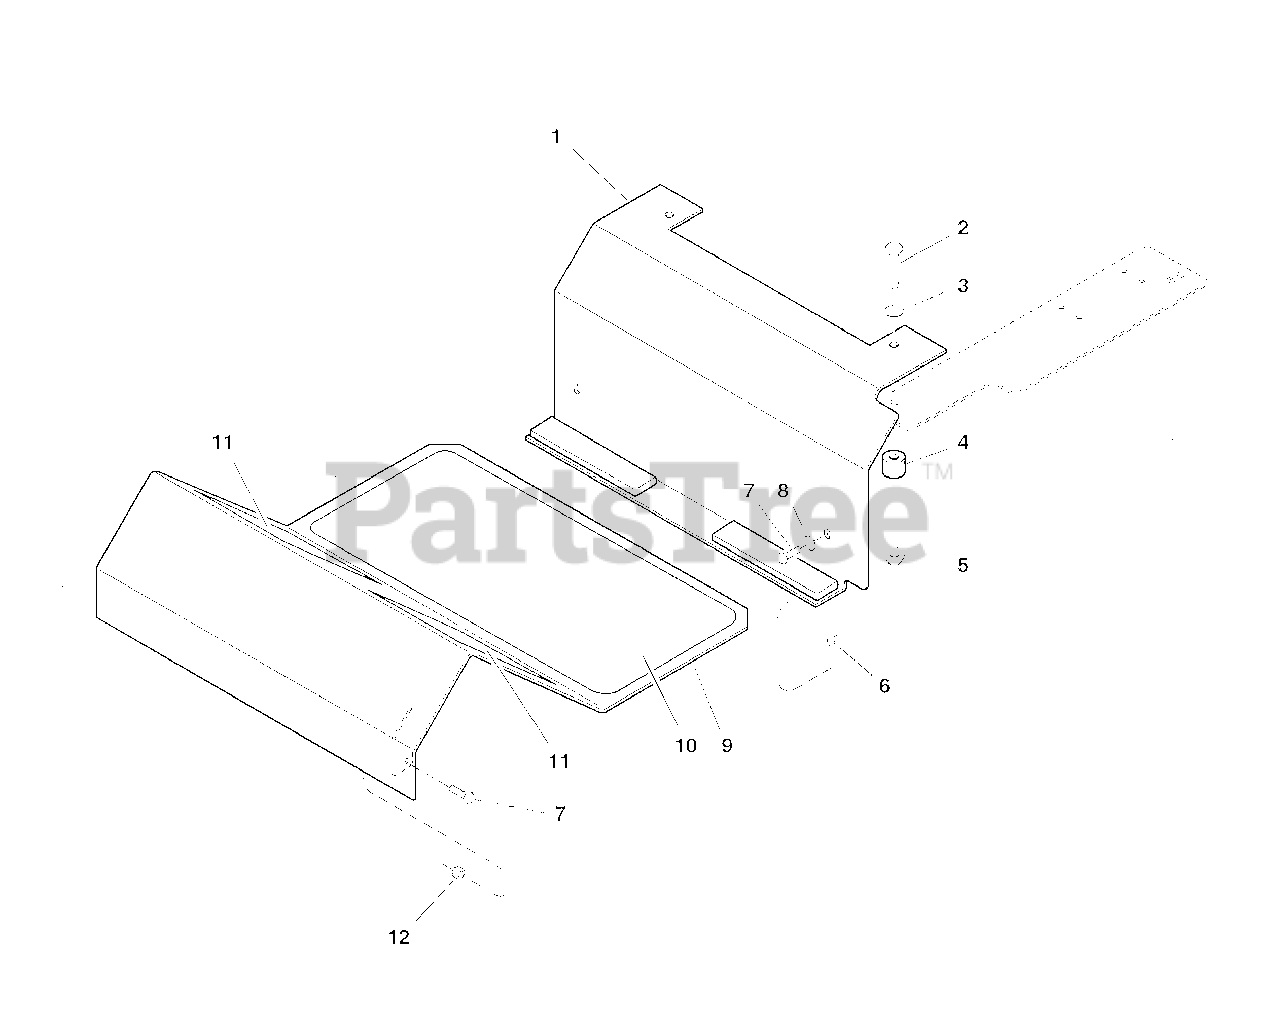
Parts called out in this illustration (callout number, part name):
1	BRAKE COVER PANEL
2	CAPSCREW, Hex Hd, 3/8-16 x 2
3	WASHER, 3/8
4	SPACER, Cover Panel
5	NUT, Hex, Serrated Flange, 3/8-16
6	BODY CLIP, 5/16-18
7	CAPSCREW, Hex Hd, 5/16-18 x 1
8	WASHER, 5/16
9	FLOOR PLATE
10	SAFETY WALK
11	SAFETY WALK
12	NUT, Hex, Nylon Lock, 5/16-18
